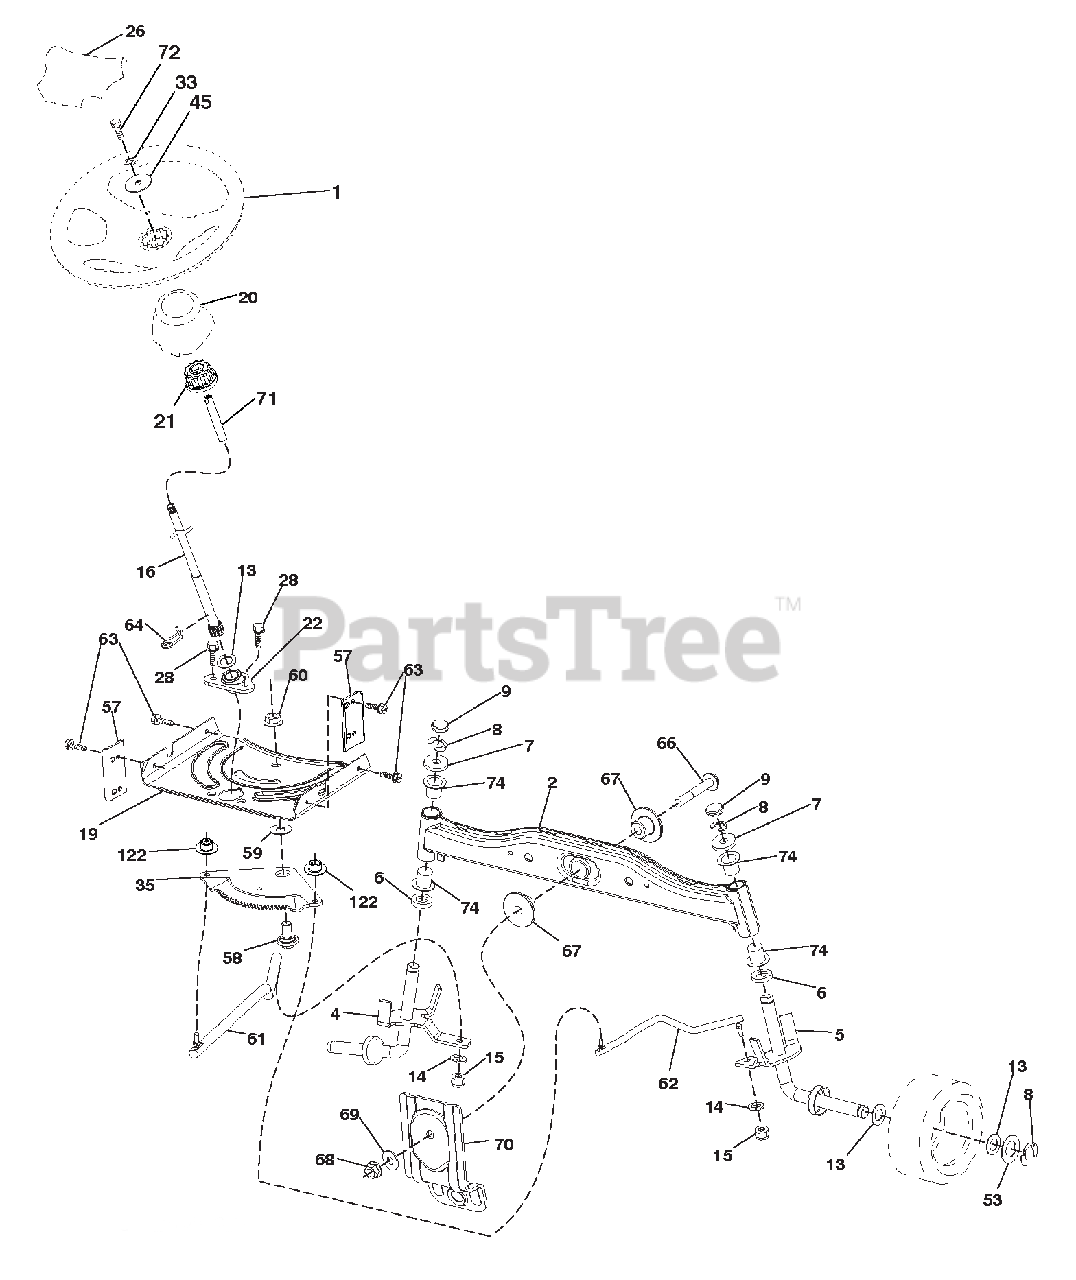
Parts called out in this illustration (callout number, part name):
1	WHEEL.STEERING.HARD RIM.BLACK
2	AXLE.CAST IRON
4	SPINDLE.WELDED.LH.15"TEX
5	SPINDLE.WELDED.RH.15"TEX
6	WAHSER THRUST .75 X 1.230
7	WASHER.25/32 X 1-5/8 X 16GA.
8	RING.KLIP.#T5304-75
9	CAP.SPINDLE.FR.TOP.BLK.
13	WASHER.25/32 X 1 1/4 X 16 GA.
14	Washer, Lock 3/8
15	NUT.CROWNLOCK.3/8-24
16	SHAFT.STEER.3/4 TEX.NON-PLATED
19	PLATE.STEER.DDL.NLT/NGT
20	BOOT.STEERING
21	ADAPTER.WHEEL.STRG..760
22	STEERING SUPT.LOWER
26	CAP WHEEL STEERING HRS/SRS BLK
28	SCREW.HEXWSH THDR3/8-16X3/4.BL
33	Washer, Lock 5/16
35	GEAR SECTOR.PLATE.DDL.NLT/NGT
45	WASHER.11/32ID X2 3/8OD X 12GA
53	WASHER.HARDEN..793 X 1.637X060
57	BRACKET.UPSTOP.TEX
58	BOLT.SHOULDER.SECTOR.PIVOT.CFM
59	WASHER.THRUST.SECTOR.STEER.NLT
60	NUT.FLANGE LOCK.5/8-11
61	DRAGLINK.LH.BALLSTUD.DDL.
62	DRAGLINK.RH.BALLSTUD.DDL
63	SCREW.5/16-18X3/4.SMGML.TAP/BL
64	RETAINER.CLIP.SPRING.STEERING
66	BOLT.HEX.FGHD.7/16-14 X 3.SERR
67	BUSHING.PM.FRONT AXLE
68	NUT.LOCK.FLANGE.7/16-14.GR5
69	WASHER.1.5 X .505 X .118
70	BRACKET.DECK.SUSPENSION.FRONT
71	Extension Steering
72	Bolt 5/16-18 x 14 w/Patch
74	BEARING COL STRNG BLK
122	CAP GEAR SECTOR
